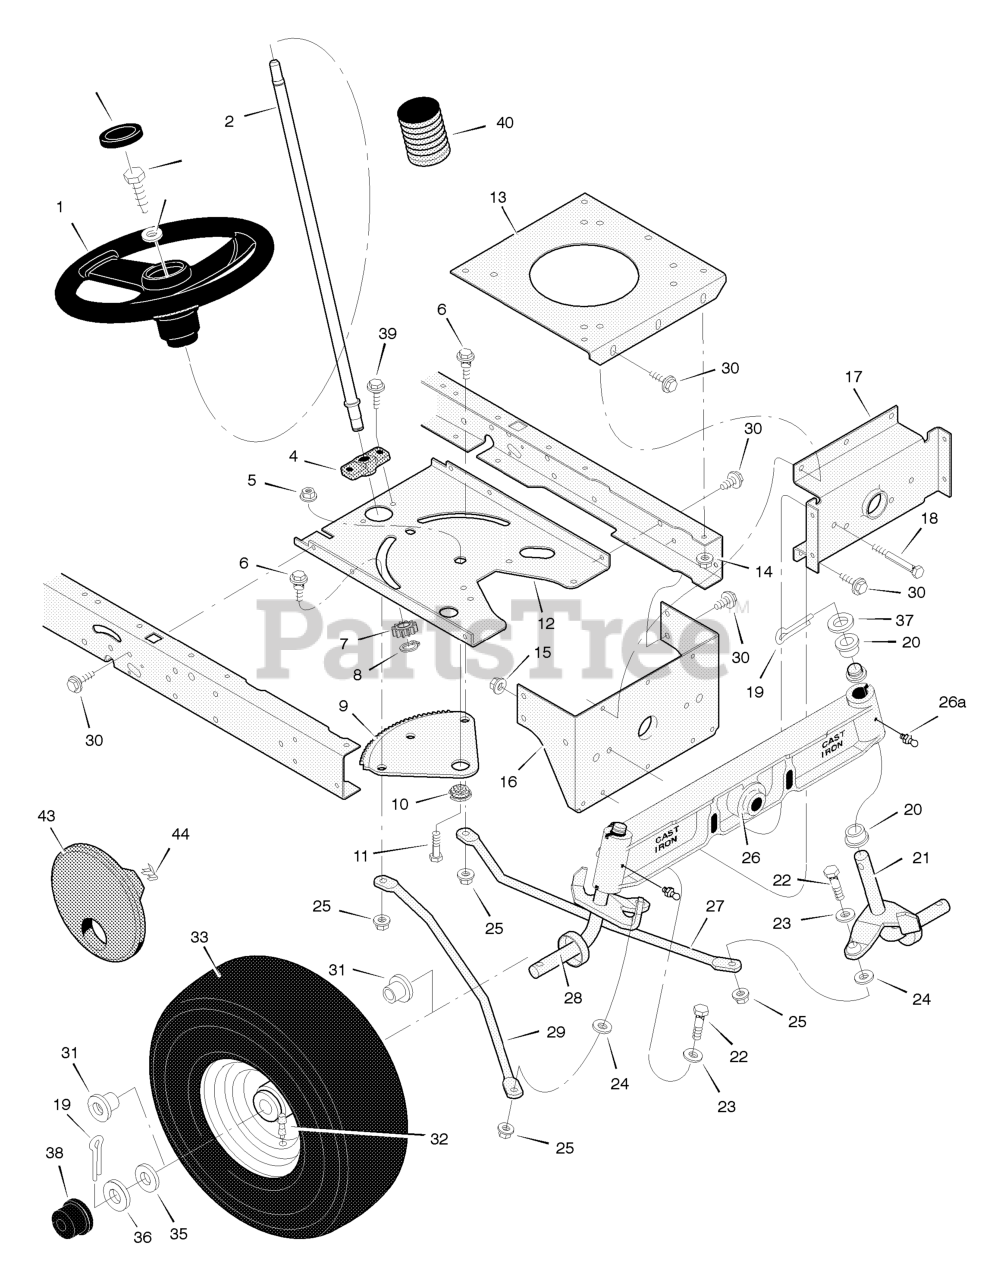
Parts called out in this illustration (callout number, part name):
1	Wheel, Steering
2	Post, Steering
3	Insert, Steering Wheel
4	Bearing
5	Nut, Flange
6	Bolt, Shoulder
7	Gear, Pinion
8	Ring, Snap
9	Gear, Sector
10	Bearing
11	CAPSCREW, Hex Head, 5/16-18 x 1
12	Plate, Steering
13	Plate, Engine
14	Nut, Flange
15	Nut, Flange
16	Bracket, Hanger
17	Axle, Hanger
19	Pin, Cotter
20	Bearing
21	Spindle Assembly, Left
22	Bolt
23	Washer
25	Nut, Flange
26	Axle Assembly
26A	Fitting, Grease
27	Drag Link, Left
28	Spindle Assembly, Right
29	Drag Link, Right
31	Bearing, Wheel
32	Stem, Valve
34	Wheel and Tire Assembly
38	Hub Cap
40	Bellows
41	Screw, Hex
42	Washer
43	Cap, Hub
44	Retainer
